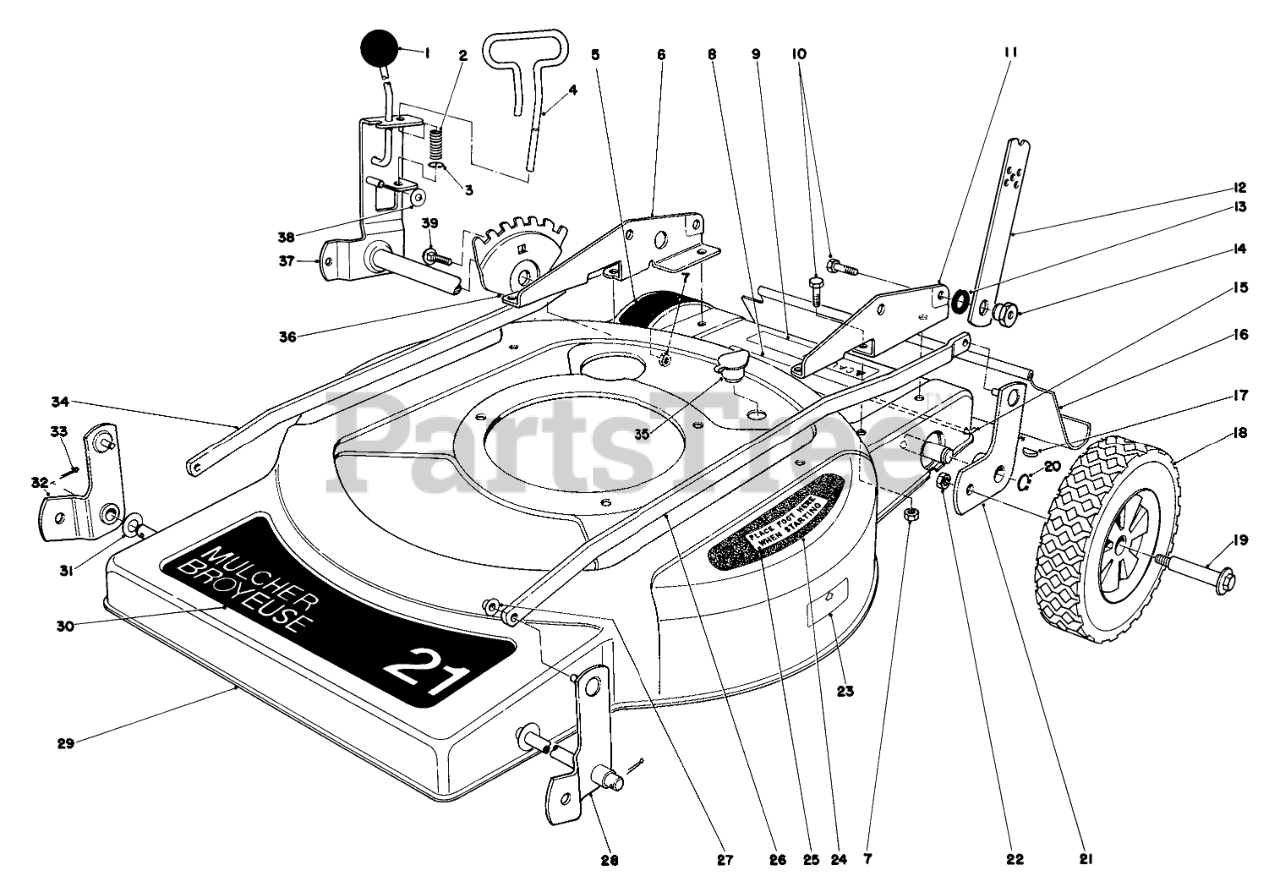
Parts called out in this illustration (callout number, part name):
2	SPRING-COMPRESSION
3	E-RING
4	STOP ROD
5	Decal Height of Cut
6	Bracket Handle R.H.
7	NUT-LOCK, CONE
8	Decal Caution
9	Caution Decal
10	SCREW-HH
11	Bracket-Handle R.H.
12	HANDLE LATCH
13	SPACER
14	HANDLE PIVOT NUT
15	SHIELD ROD
16	SHIELD - TRAILING
17	KEY-WOODRUFF
18	WHEEL TIRE ASM 8 IN
19	BOLT-WHEEL
20	RING-RETAINING
21	Pivot Arm
22	Nut
23	Decal Step
24	PAD STEP
25	Decal Step Pad
26	Spanner Link L.H.
27	NUT-SPEED
28	LH FRT PIVOT ARM WA
29	Housing
30	Decal-Front Deck
31	WASHER
32	Pivot Arm
33	PIN-COTTER
34	Spanner Link R.H.
35	WASHOUT PLUG
36	HOC ADJUSTMENT PLT
37	Pivot Arm Bracket
38	WASHER-FLAT
39	Carriage Bolt
